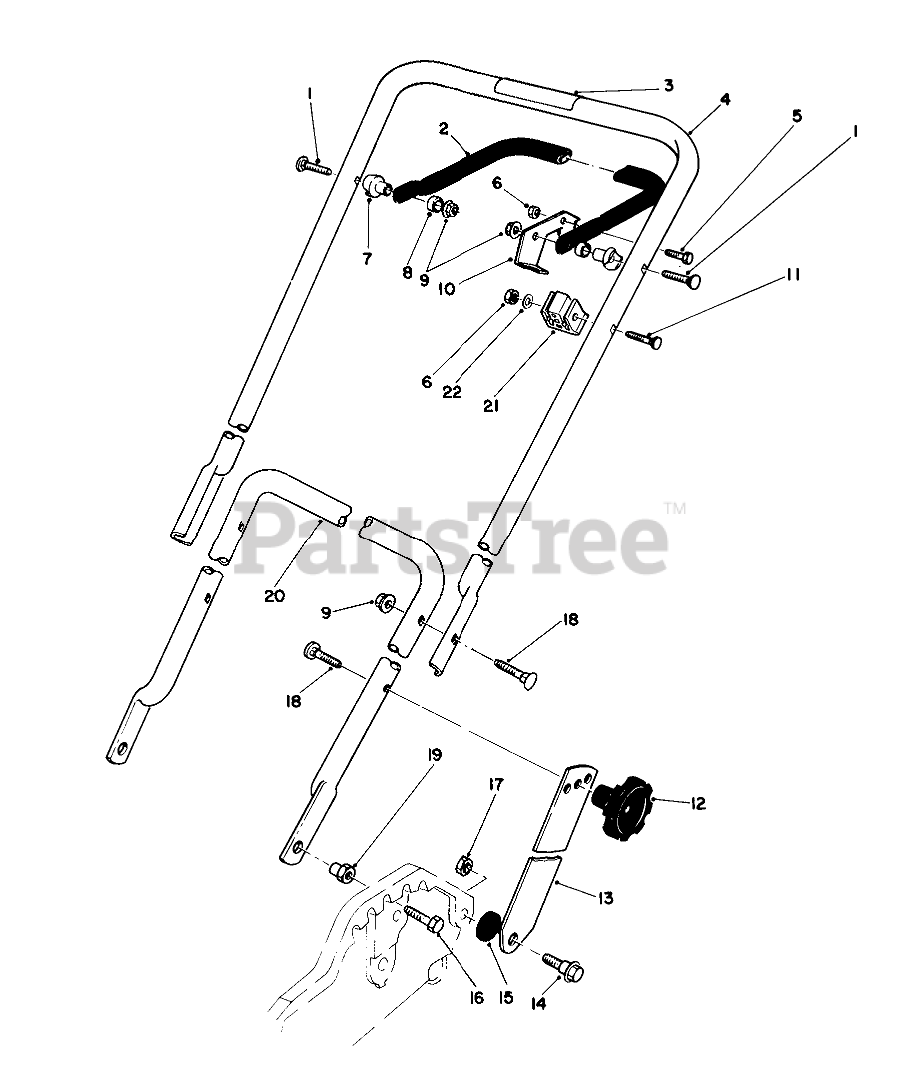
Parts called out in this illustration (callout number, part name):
1	5/16-18 X 2 HNDLE SCREW
2	Bar-Control
3	Decal-Danger
4	Handle-Upper
5	SCREW-HH
6	NUT-LOCK, NI
7	SPACER-SUPPORT
8	SPACER-NYLON
9	NUT-LOCK, NI
10	Lever-Control
11	HANDLE SCREW
13	Handle Latch
14	SCREW-SHOULDER
15	SPACER
16	SCREW-HH
17	NUT-LOCK, NI
18	SCREW
19	HANDLE PIVOT NUT
20	LOWER HANDLE
21	SUPPORT-CABLE
22	WASHER-FLAT
